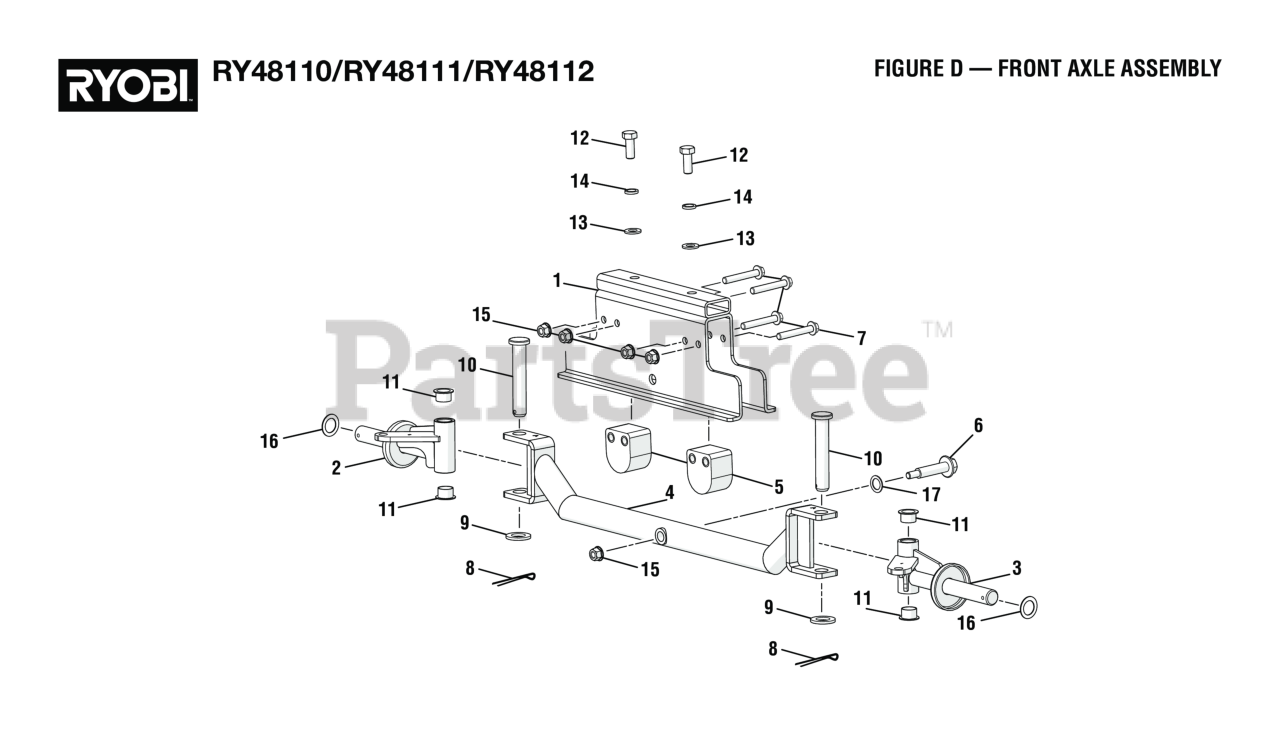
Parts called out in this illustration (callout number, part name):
1	Front Axle Channel Plate w/Brackets
2	Right Steering Knuckle
3	Left Steering Knuckle
4	Front Axle
5	Front Axle Rubber Bumper Assembly
6	Shoulder Bolt (M8 x 60 mm, Flange Hex Hd.)
7	Bolt (M8 x 55 mm, Flange Hex Hd.)
8	Cotter Pin (4 x 40 mm)
9	Washer (OD30 x ID17 x 3t)
10	Steering Knuckle Anchor
11	Steering Knuckle Bushing
12	Bolt (M10 x 45 mm, Hex Hd.)
13	Washer (OD20 x ID10.5 x 2t)
14	Lock Washer (M10)
15	Flange Nut (M8) (For Drive Motor Controller V)
16	Washer (OD28 x ID20.5 x 2t)
17	Washer (OD24 x ID13 x 2.5t)
